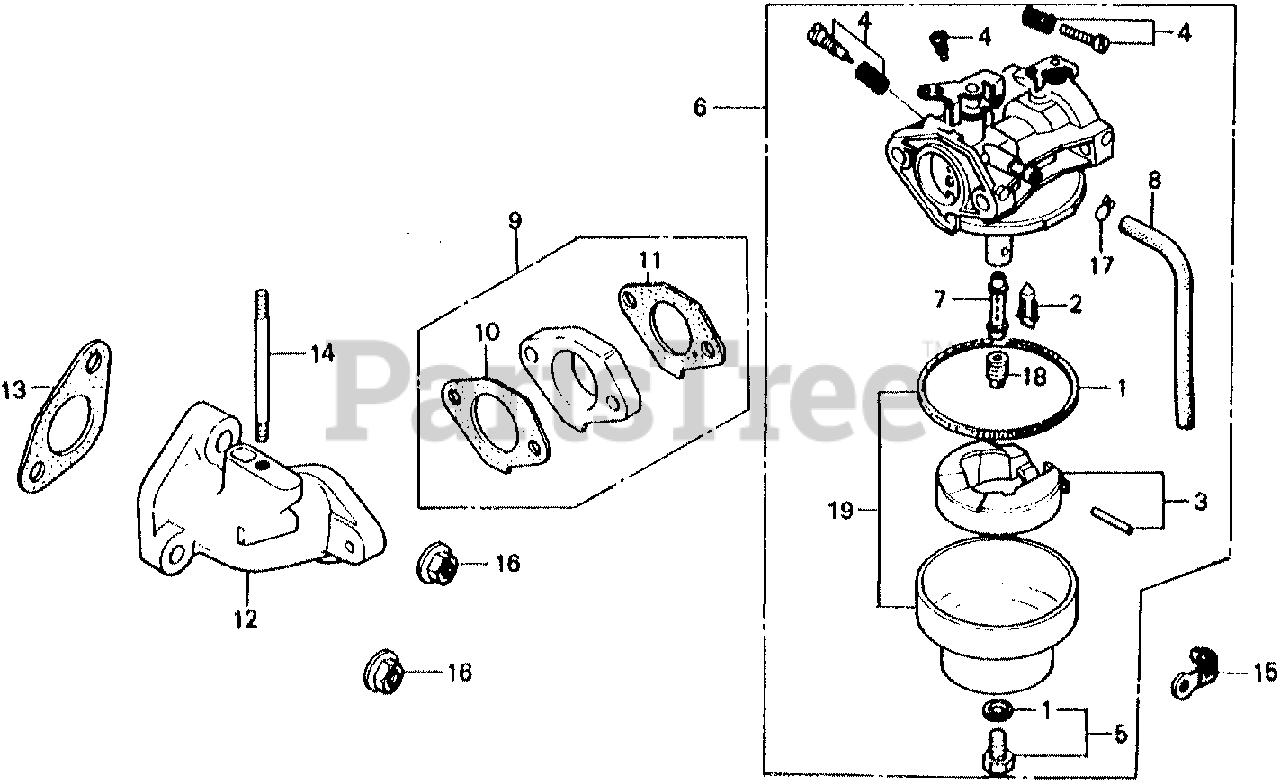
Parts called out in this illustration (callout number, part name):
1	GASKET SET
2	VALVE SET, FLOAT
3	FLOAT SET
4	SCREW SET A
5	SCREW SET B
6	CARBURETOR ASSY. (BB38A H)
7	NOZZLE, MAIN
9	INSULATOR, CARBURETOR
10	GASKET, INSULATOR
11	GASKET, CARBURETOR
12	MANIFOLD, IN.
13	GASKET, IN. MANIFOLD
14	BOLT, STUD (6X87)
16	NUT, FLANGE (8MM)
18	JET, MAIN (#92)
18	JET, MAIN (#95)
18	JET, MAIN (#98)
18	JET, MAIN (#100)
18	JET, MAIN (#102)
18	JET, MAIN (#105)
19	CHAMBER SET, FLOAT
